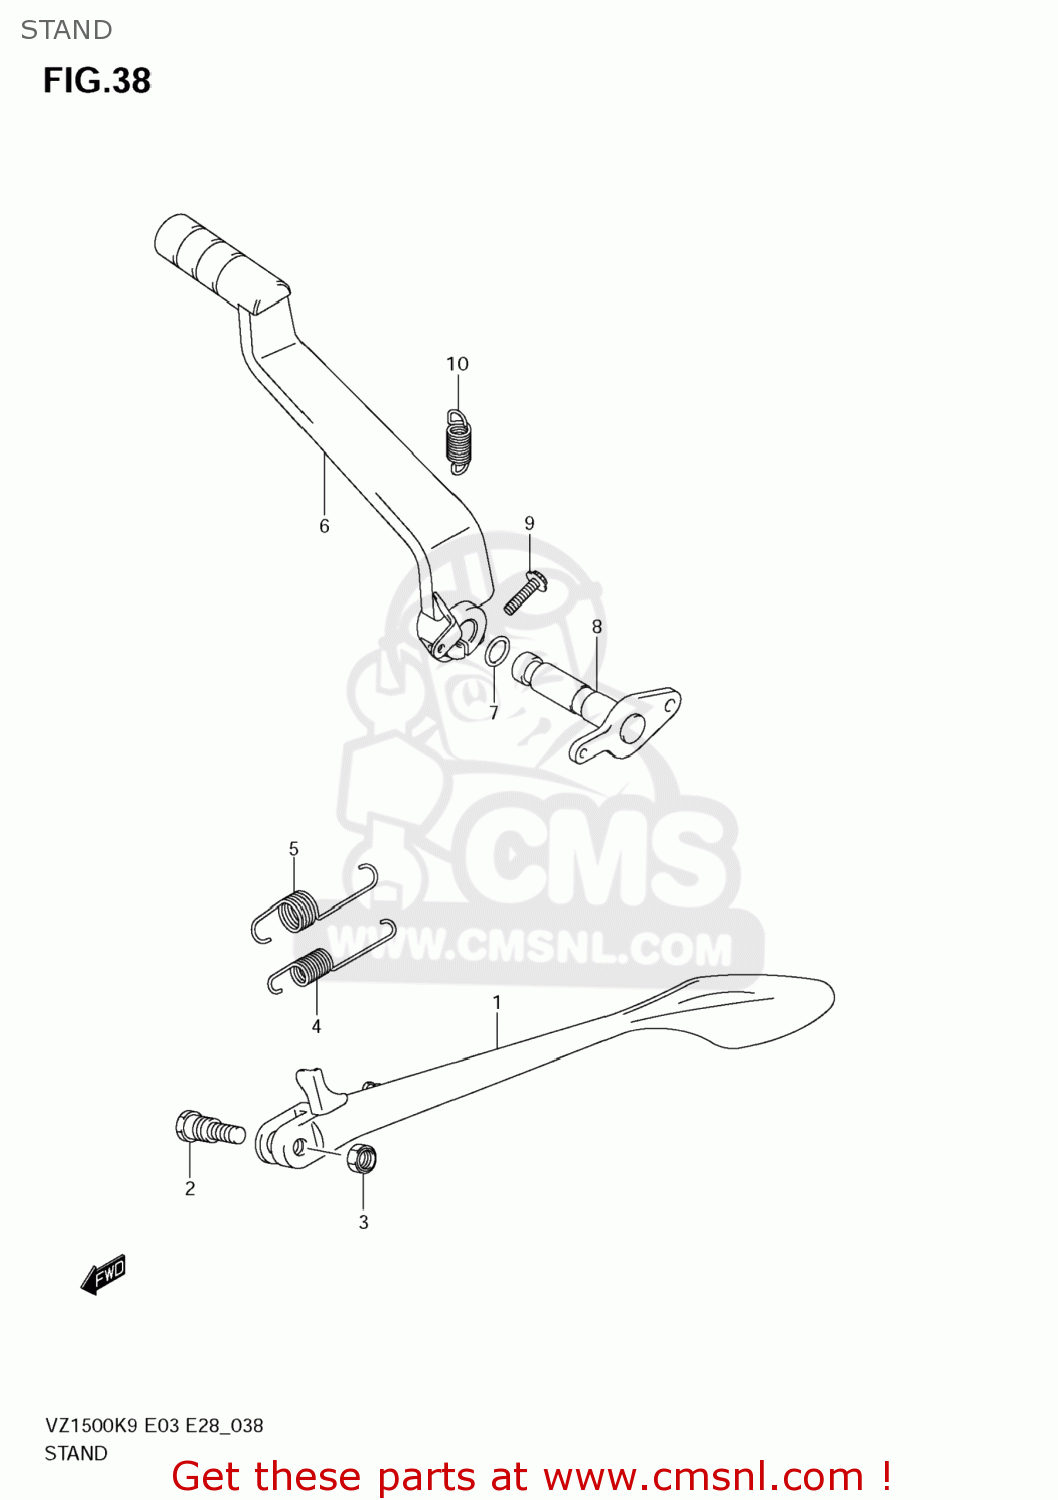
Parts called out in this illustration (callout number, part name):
1	STAND,PROP
2	BOLT(10X37.5)
3	NUT,PROP STAND
4	SPRING
5	SPRING
6	PEDAL COMP,BRA
7	O RING(D:2.5,ID:13.8)
8	ARM,BRAKE ROD
9	BOLT
10	SPRING
